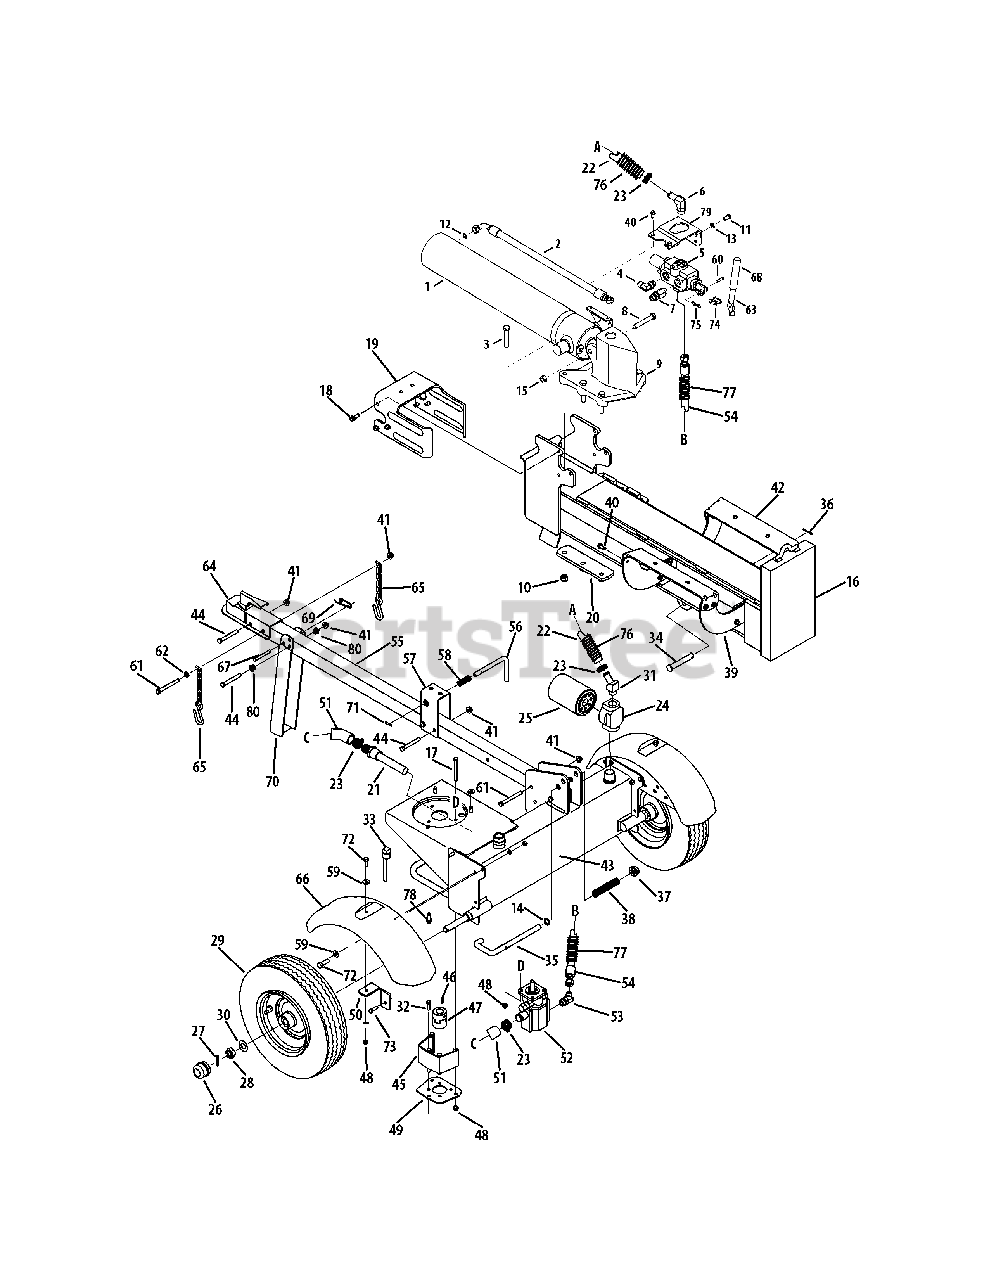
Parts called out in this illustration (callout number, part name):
1	Hydraulic Cylinder
2	Hydraulic Tube
3	Hex Cap Screw, 1/2-20 x 2.75
4	90 Degree Solid Adapter
5	Control Valve
6	Return Elbow
7	Nipple Pipe, 1/2-14
8	Hex Cap Screw, 1/2-13 x 3.25
9	Wedge Assembly
10	Hex Lock Nut, 1/2-20
11	Hex Cap Screw, 3/8-16 x .75
12	O-Ring, .419 ID x .070 Dia.
13	Lock Washer, 3/8
14	Flat Washer, .635 x.93 x.06
15	Hex Lock Nut, 1/2-13
16	Beam Assembly
17	Hex Screw, 5/16-18 x 3.25
18	Self Tapping Screw, 3/8-16 x 1.0
19	Dislodger Bracket
20	Back Plate
21	Inlet Filter
22	Return Hose, 3/4 x 44
23	Hose Clamp, 5/8
24	Filter Housing
25	Oil Filter
26	Hub Cap
27	Cotter Pin
28	Slotted Nut, 3/4-16
29	Complete Wheel Assembly
29	Wheel/Rim Assembly
29	Dust Seal
29	Roller Bearing
30	Flat Washer, .760 x.500
31	Adapter, 3/4-14
31	Hydraulic Fitting, 1 1/16 Orb x .75
32	Hex Screw, 5/16-18 x 1.00
33	Vented Dipstick
34	Clevis Pin
35	Lock Rod
36	Cotter Pin
37	Push Cap
38	Compression Spring
39	Log Tray Bracket
40	Hex Washer Screw, 5/16-18 x .750
41	Flange Lock Nut, 3/8-16
43	Frame Assembly
44	Hex Bolt, 3/8-16 x 3
45	Coupling Shield
46	Square Key, 3/16" x .75
47	Flexible Coupling .875 X .500
47	Spider Bushing
47	Flexible Coupling .500
47	Flexible Coupling .875
47	Set Screws
48	Flange Lock Nut, 5/16-18
49	Rear Coupling Support Bracket
50	Fender Mounting Bracket
51	Hose
52	Gear Pump
53	45 Degree Elbow Fitting
54	High Pressure Hydraulic Hose
55	Tongue Assembly
56	Latch Rod
58	Compression Spring
59	Flat Washer
60	Clevis Pin
61	Hex Cap Screw, 3/8-16 x 3.50
62	Flat Washer, .375 x.738 x.063
63	Hydraulic Valve Control
64	Hitch Coupling Assembly
66	Fender
67	Clevis Pin
69	Spring Pin
70	Jack Stand
71	Spiral Pin
72	Self-Tapping Screw, 5/16-18 x 0.875
73	Self-Tapping Screw, 5/16-18 x 1.00
74	Valve Handle Link
75	Cotter Pin, Bow Tie
76	Hose Guard, 44"
77	Hose Guard, 48"
78	Sems Screw, 3/8-16 x 1.250
79	Outer Valve Bracket
80	Plastic Bushing, .380 ID
